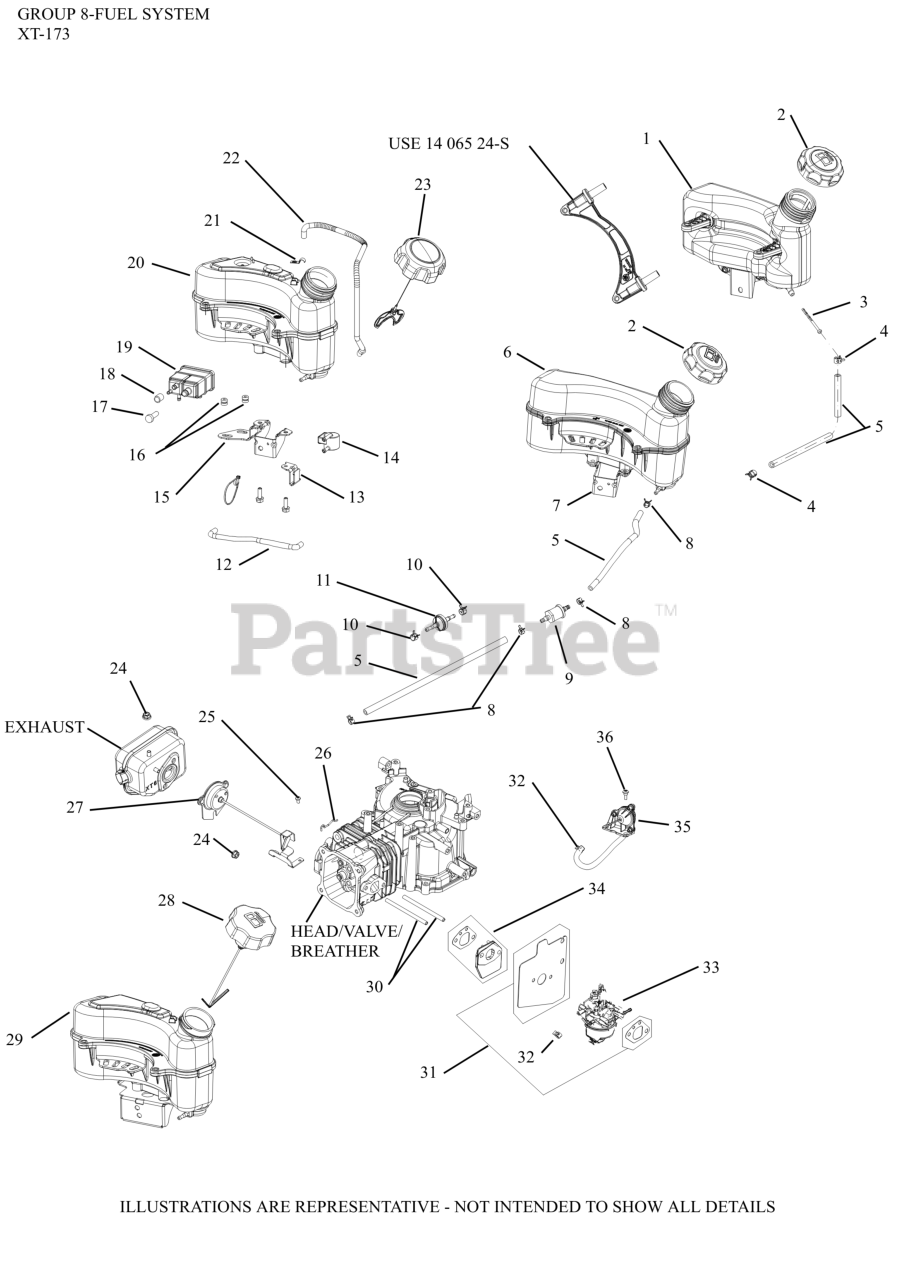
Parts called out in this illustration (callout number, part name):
1	KIT, TANK ASSY, NON-CALIFORNIA
2	CAP, FUEL ASSEMBLY
3	FILTER, FUEL IN-NIPPLE
4	CLAMP, HOSE (NON-CALIF)(#1423710S)
5	HOSE, FUEL LOW-PERMEATION (CKY)
30	STUD,M6X1.0X100.2MM
31	KIT, GASKET-USE 14 041 31-S
33	KIT, CARBURETOR-USE 14 853 60-S
NI	KIT, SPACER
NI	KIT, HIGH ALTITUDE (4,000-8,000 FT)
NI	KIT, CARB REPAIR - USE 14 757 03-S
